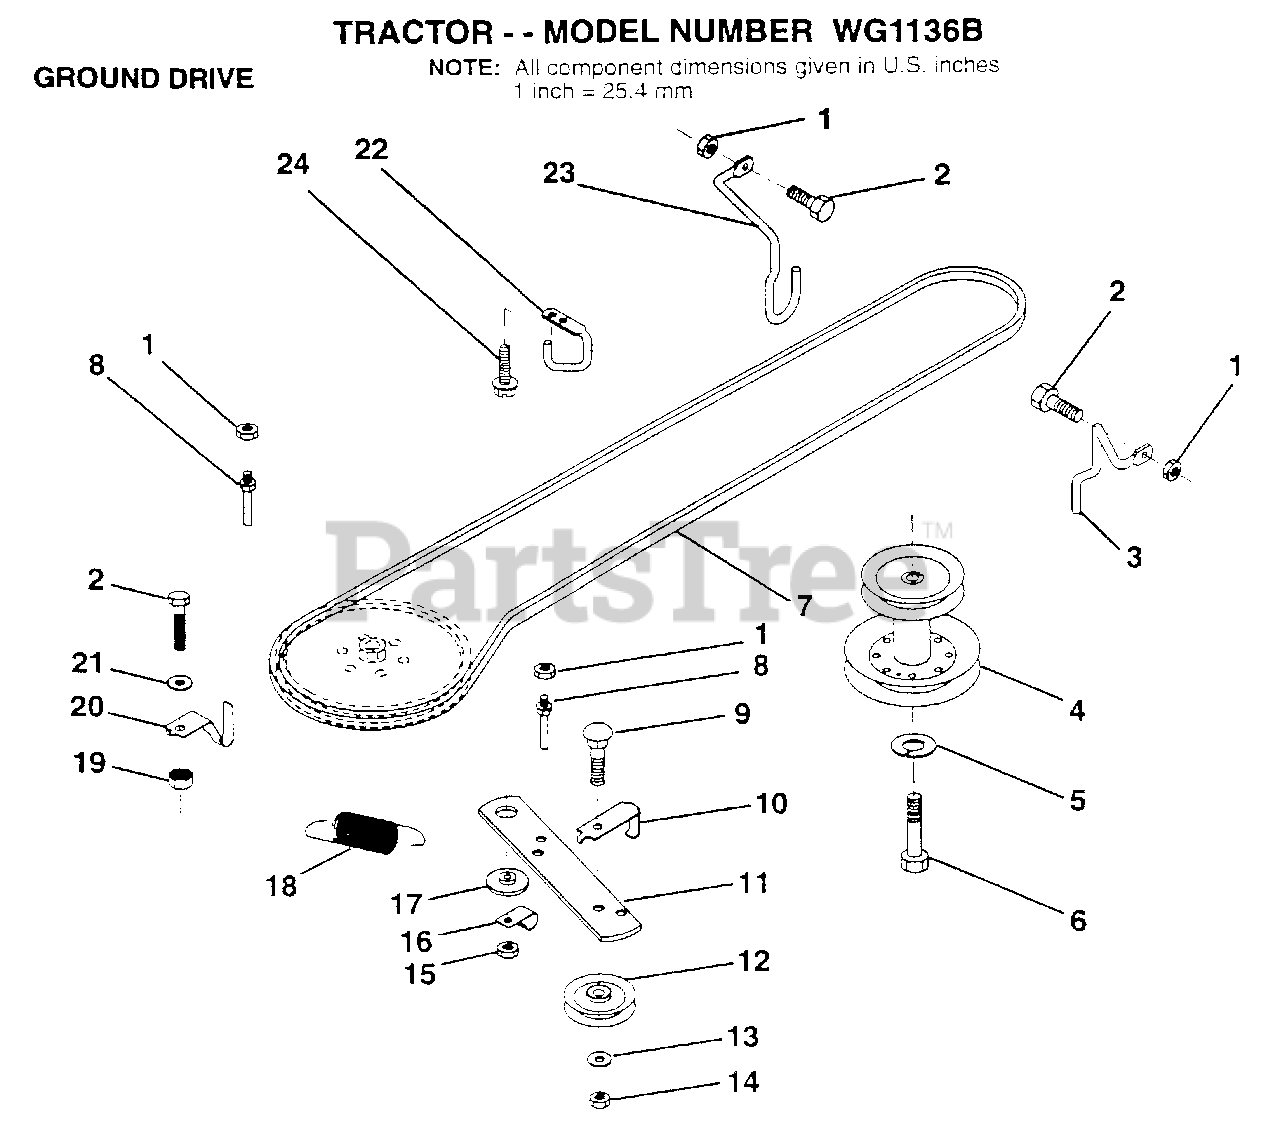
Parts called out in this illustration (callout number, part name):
2	BOLT
3	KEEPER RH
4	PULLEY.ENGINE.LR
5	LOCKWASHER
6	HEX BOLT
7	BELT
8	"KEEPER,DRIVE BELT"
9	BOLT
10	"KEEP,IDLER DR BEL"
11	ARM IDLER CLUT GD
12	PULLEY.IDLER.FLAT
13	WASHER
14	LOCKNUT
16	"CLIP,INSULATOR"
17	SPACER RETAINER
20	KEEPER.BELT.T/A
21	WASHER
22	"KEEPER,FRA DR BEL"
23	KEEPER MOWER LH
24	SCREW
